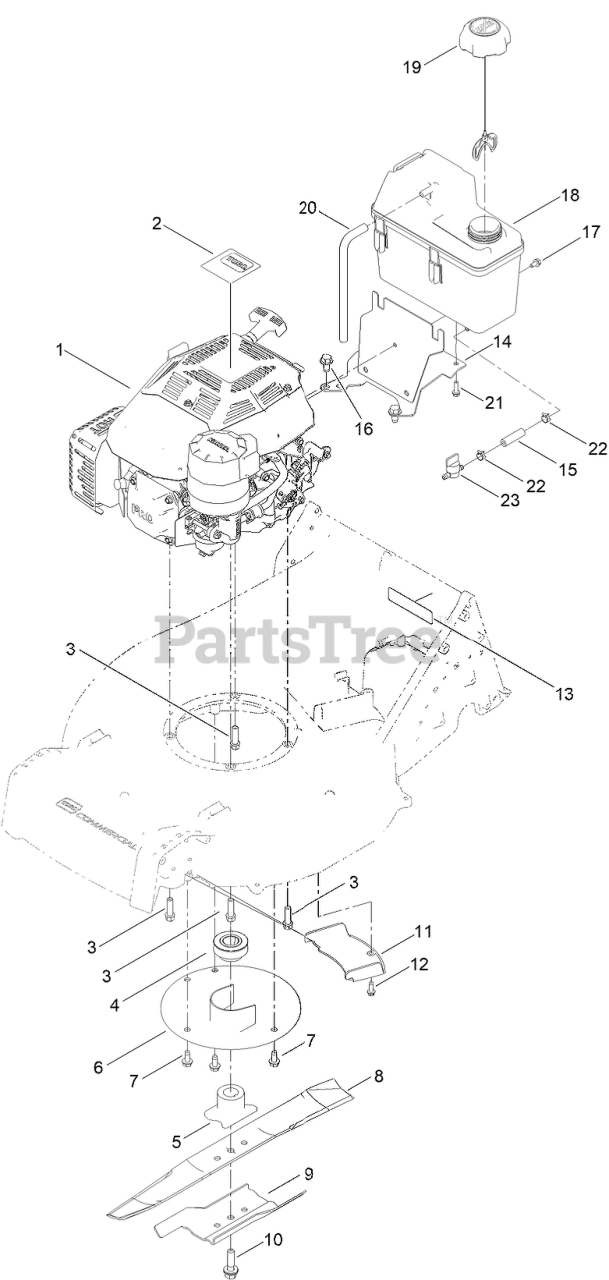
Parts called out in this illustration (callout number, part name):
2	DECAL-KOHLER
3	SCREW-TAPTITE
4	PULLEY-DRIVER
5	DRIVER-BLADE
6	PROTECTOR-CRANKSHAFT
7	SCREW-HWHTF
8	BLADE-21IN, RECYCLING
9	ACCELERATOR-BLADE
10	BOLT-BLADE
11	COVER-BELT
12	SCREW-HWHTF
13	DECAL-ARRESTOR, SPARK
14	TANK MOUNT ASM
15	HOSE-FUEL
16	SCREW-HWH
17	SCREW-HWH
18	TANK-FUEL
19	CAP-FUEL
20	HOSE-VENT, CANISTER
21	SCREW-HWH
22	CLAMP-HOSE
23	VALVE-FUEL
